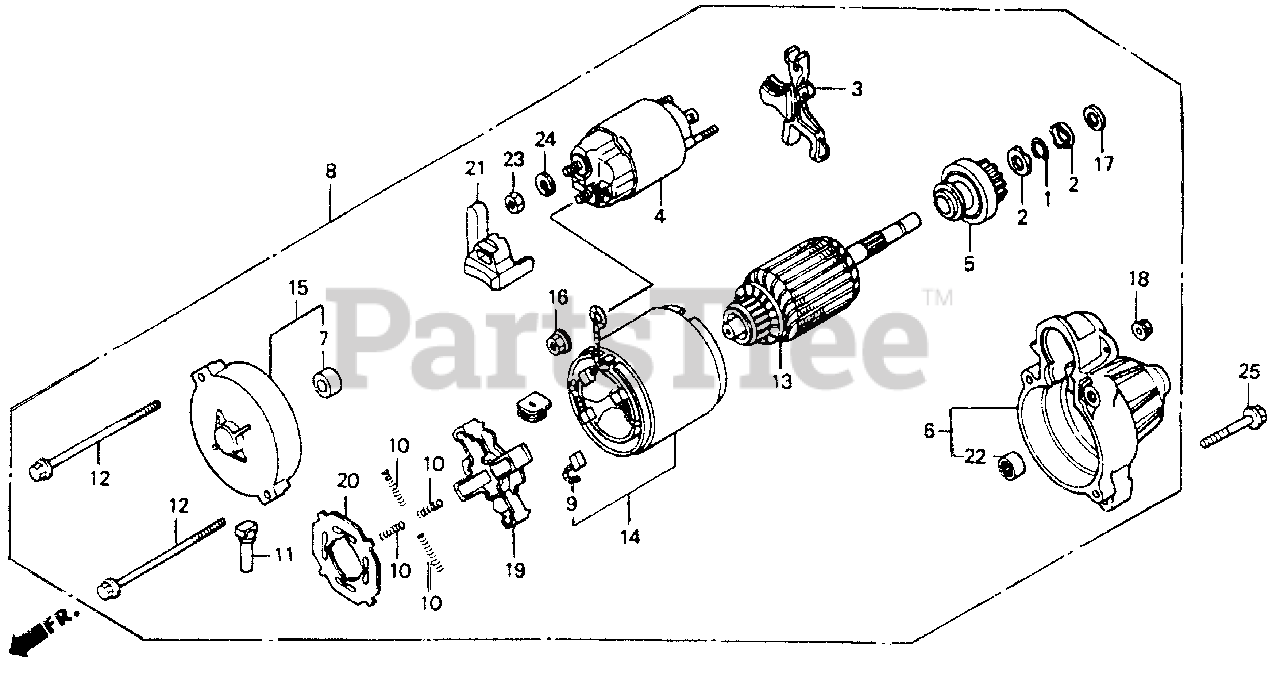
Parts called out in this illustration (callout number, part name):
1	RING, SNAP (DENSO)
2	COLLAR, CLUTCH STOP
2	COLLAR SET, CLUTCH STOP
3	LEVER, PINION DRIVE
4	SWITCH ASSY., MAGNETIC
5	CLUTCH, OVERRUNNING
6	HOUSING, SIDE DRIVE
7	BEARING B
8	MOTOR ASSY., STARTER
9	BRUSH
10	SPRING, BRUSH
11	COVER, RR.
12	BOLT, THROUGH
13	ARMATURE
14	YOKE
15	FRAME, COMMUTATOR END
16	NUT, HEX. (8MM)
17	WASHER
18	NUT, FLANGE (5MM)
19	HOLDER, BRUSH
20	INSULATOR, BRUSH HOLDER
21	COVER, TERMINAL
22	BEARING A
23	NUT, HEX. (8MM)
24	WASHER, SPRING (8MM)
25	BOLT, FLANGE (8X40)
